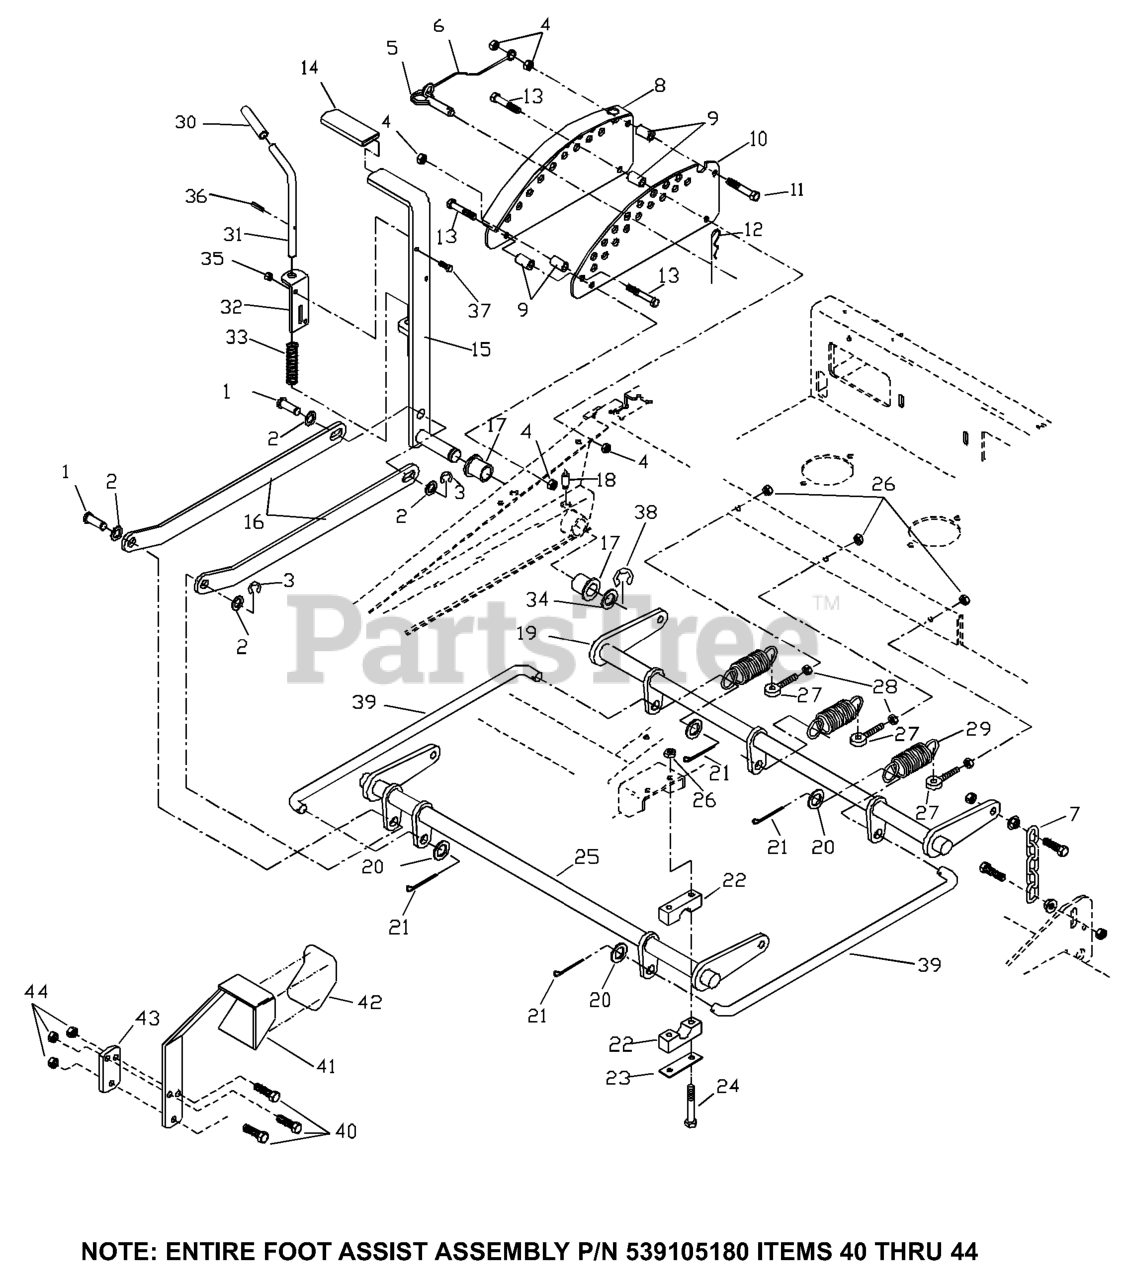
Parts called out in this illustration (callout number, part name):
1	CLEVIS PIN
2	BUSHING
3	E-RING 5/8
4	NUT 3/8C CENTERBLOCK
7	LIFT CHAIN
8	ADJ. PLATE WLDMNT
9	DECK LIFT SPACER
10	ADJ. PLATE PAINTED
11	HCS 3/8C X 2 1/2
12	HAIRPIN #4
13	HCS 3/8C X 2 1/4
15	LIFT LEVER WLDMT
16	LIFT LINKAGE,PAINTED
17	BUSHING, FLANGED
18	GREASE ZERK LONG
19	LIFT SHAFT
20	WASHER 5/8 FLAT
21	COTTER PIN
22	PILLOW BLOCK
23	REINFORCEMENT BAR
24	BOLT 5/16C X 2 1/2
25	FT. LIFT SHAFT
26	NUT 5/16C CENTERLOCK
27	EYEBOLT, RH
28	NUT 5/16C WHIZ
29	DECK LIFT SPRING
32	PIN MT, UPPER
34	BSHG .875 X 1.375 X .074 ZD
35	NUT 1/4C CENTER LOCK
36	ROLL PIN 3/16 X 1-1/4 ZD
37	HCS 1/4C X 3/4 HCS
38	E-RING 7/8
39	CONNECTING LINK
40	HCS 3/8C X 1 1/2
41	LIFT PEDAL BLK
42	ANTI-SKID PAD
43	TIGHTENING PLATE BLK
44	NUT 3/8-16 NYLOC
539105180	FOOT ASSIST DECK LIFT-GEN II
